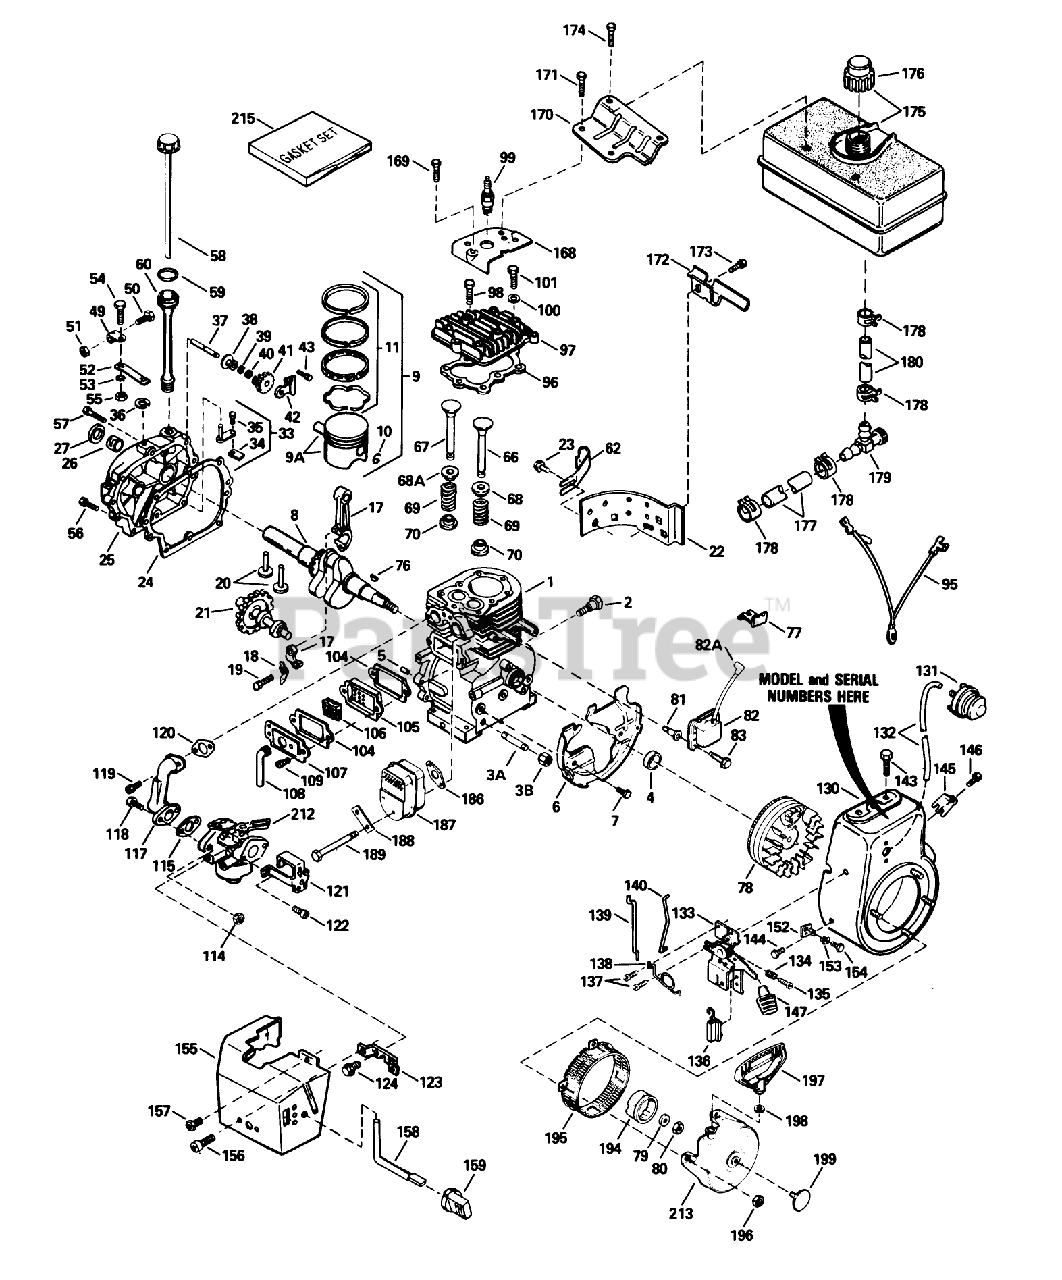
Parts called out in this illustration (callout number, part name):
1	Cylinder Asm (Includes 2, 20, 72)
2	Screw (1/4-20x1/2)
3A	Nipple-Pipe
3B	Cap-Pipe
4	Seal-Oil
5	Pin-Dowel
6	Baffle-Blower Housing
7	Screw (1/4-20x19/32)
8	Crankshaft
9	Piston, Pin Ring Assy.(Std.) (Incl. Ref. #24A, 25 26)
9A	Piston Pin Assy. (Std.) (Incl. Ref. #26)
11	Ring Set (Std.)
17	Rod Assy., Connecting (Incl. Ref. #26 27)
18	Dipper-Oil
19	Bolt-Rod
20	Lifter-Valve
21	Camshaft (MCR)
22	Extension-Housing, Blower
23	Screw
24	Cylinder Cover Gasket
25	Cover-Cylinder (Includes 71, 75, 80)
26	2025A77 WIZARD ROTA
27	Seal-Oil
33	Rod, Governor (Incl. Nos.62 63)
34	Yoke-Governor
35	Screw (6-40x5/16)
36	Ring-Retaining
37	Shaft-Governor
38	Spool-Governor
39	Washer-Flat
40	Ring-Retaining
41	Gear Assy., Governor (Incl. Ref. #45)
42	Bracket-Gear, Governor
43	Screw (10-24x1/2)
49	Clamp-Lever, Governor
50	Screw
51	Nut-Lock
52	Lever-Governor
53	Washer-Lock
54	Screw
55	Nut-Lock
56	Screw (1/4-20x1-11/16)
57	Screw (1/4-20x1-3/16)
58	Dipstick
59	O-Ring
60	Tube-Fill, Oil
62	Clip-Tube, Fill
66	Valve, Exhaust (Standard)(Incl. No. 9)
67	Valve, Intake (Std.) (Incl. Ref. #58)
68	Cap-Spring, Valve
68A	Seal-Intake Valve
69	Spring-Valve
70	Keeper-Spring, Valve
76	Key-Flywheel
77	Clip-Wire
78	Flywheel (W/Ring Gear)
79	Washer-Belleville
80	Nut-Flywheel
82	Solid State ASM
82A	Cover-Spark Plug
83	Screw
95	Ground Wire
96	Gasket-Cylinder Head
97	Head Cylinder
98	Screw (5/16-18x1-1/2)
99	Spark Plug-Resistor (R J19 L M)
100	Washer-Flat
101	Screw (5/16-18x1-25/32)
104	Gasket-Breather
105	Body-Breather
106	Element-Breather
107	Cover-Valve
108	Tube-Breather
109	Screw
114	Nut and Lock Washer (1/4-28)
115	Gasket-Carburetor To Intake Pipe
117	Pipe-Intake
118	Screw (1/4-28x1)
119	Screw (T-30, 5/16-18x1-3/32)
120	Gasket-Intake
121	Bracket-Choke
122	Screw (10-32 x 1/2)
123	Bracket-Carburetor
124	Screw (8-32x27/64)
130	Housing-Blower
131	Primer-Asm
132	Line-Primer
133	Control Bracket Assembly (Incl. Ref. #134-136 138)
134	Spring-Compression
135	Screw
136	Terminal
137	Screw (10-32 x 1/2)
138	Spring-Throttle
139	Link-Governor
140	Link-Throttle
143	Screw (5/16-18x3/4)
144	Screw
145	Screw
146	Screw (8-32 x 3/8)
147	Knob-Control
152	Bracket
153	Grommet
154	Screw (8-32 x 3/8)
155	Cover-Carburetor
156	Screw (10-32 x 3/8)
157	Screw (10-32x1/2)
158	Rod-Choke
159	Knob-Control
168	Cover-Cylinder Head
169	Screw (1/2-20x5/8)
170	Bracket-Tank, Fuel (Black)
171	Screw
172	Bracket-Tank, Fuel
173	Screw (1/4-20x19/32)
174	Screw (1/4-15x7/8)
175	Tank Assy., Fuel (Incl. No. 115)
176	Cap, Fuel
177	Line-Fuel
178	Clamp-Line, Fuel
179	Valve-Shut Off
180	Line-Fuel (8.62)
186	Gasket Exhaust
187	Muffler
188	62513 SNWTHWR W/284
189	Screw
194	Cup-Starter
195	Screen-Starter
196	Nut and Lock Washer (1/4-28)
197	Handle-Starter, Mitten Grip
198	Washer
199	Plug Starter
212	Carburetor (Incl. Ref. #75)
213	Starter-Rewind
215	Gasket Set (Incl. items marked *) Order As Accessory.
